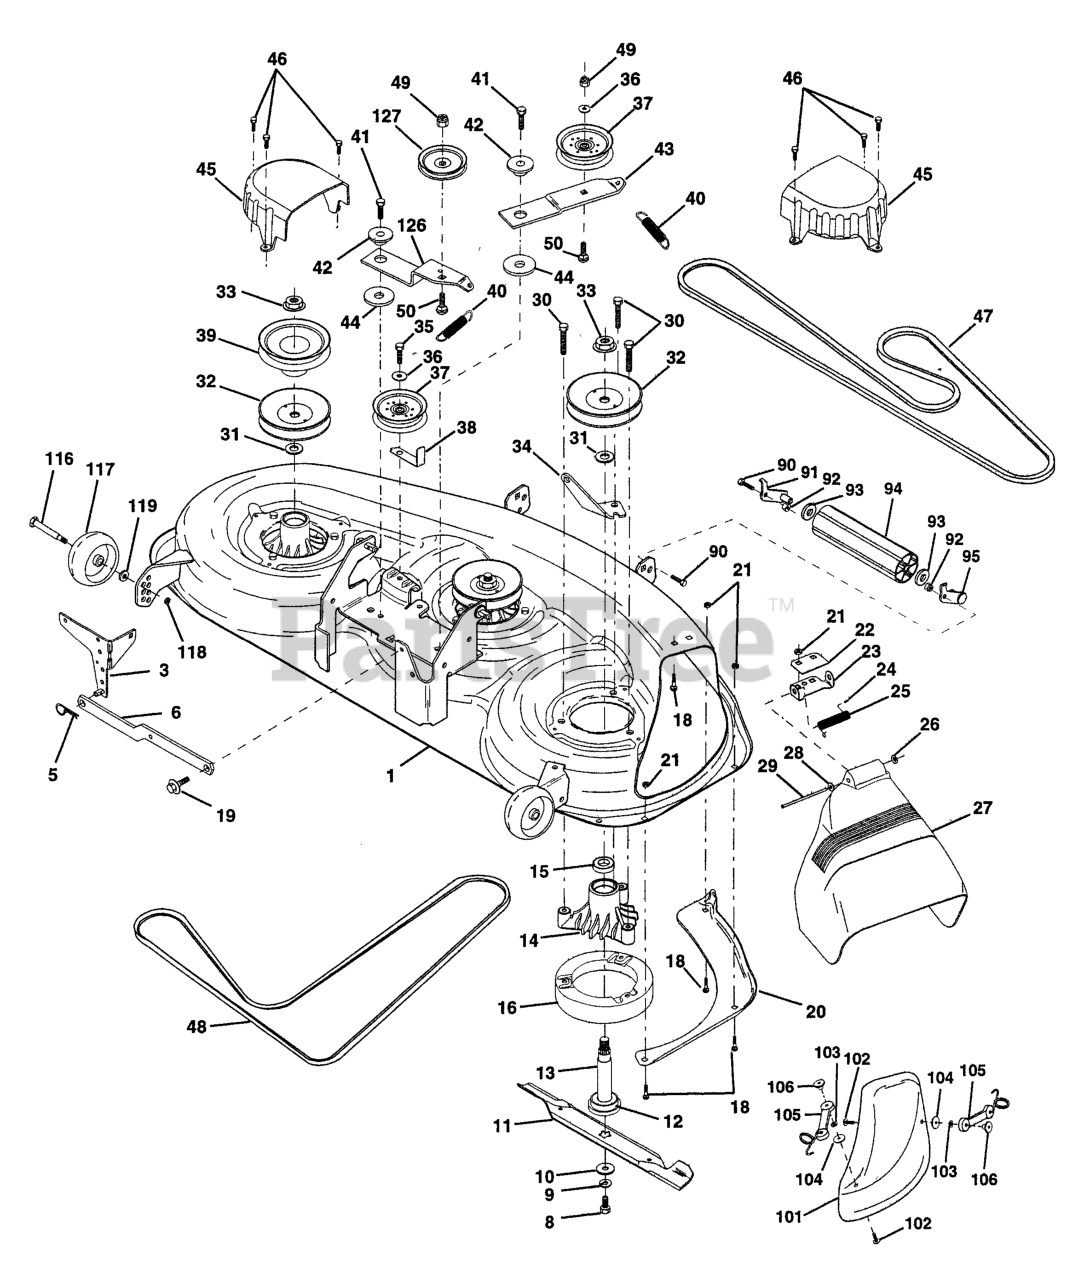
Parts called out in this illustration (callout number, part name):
1	DECK ASM, MOWER 46"
3	BRACKET SWAY BAR
5	RETAINER-SPRNG RB
6	REAR SUSP ARM
8	BLADE BOLT
9	LOCKWASHER
10	WASHER.BLADE
11	MULCH BLADE 46"
12	BEARING.BALL.#6204.(MANDREL)
13	SHAFT.ASM.W/BEARING
14	HOUSING.MANDREL.44/46" VENT
16	Stripper, Mower Round
18	BOLT
19	BOLT SHD 5/16-18
20	BAFFLE, VORTEX MOWER 46"
21	LOCKNUT
22	STIFFENER BRACKET
23	DEFLECTOR BRACKET
24	CAP-SLEEVE LT
25	SPRING TORSION
26	NUT PUSH M
27	SHIELD, DEFLECTOR MOWER
28	Washer 11/32 x 5/8 x 16 Ga.
29	ROD.HINGE
30	SCREW
31	WASHER
32	PULLEY, MANDREL
33	NUT
34	ANCHOR, SPRING DECK 46"
35	SCREW LT
36	WASHER
37	FLAT IDLER PULLEY
38	KEEPER
39	PULLEY.DRIVEN.DECK.46"
40	SPRING.SEC.44"VEN
41	SCREW
42	SPACER RETAINER
43	ARM IDLER DECK 46"
44	HARDENED WASHER
45	COVER MANDREL 46
46	SCREW.1/4-20X5/8
47	BELT V SECONDARY
48	V-BELT PRIMARY 50"
50	BOLT.3/8-16X1.50
90	BOLT
91	BRACKET LH (A)
92	NUT
93	Washer 17/32 x 7/8 x 16 Ga.
94	NOSE ROLLER
95	BRACKET RH (B)
101	COVER.MULCH.46"3-BLADE.(2 2)
102	SCREW
103	LOCKWASHER #10
105	LATCH ASSEMBLY
106	WELDNUT
116	BOLT, SHOULDER
117	WHEEL GAGE DONUT
118	LOCKNUT
119	WASHER.5/16.FLAT.STE.STD.
126	ARM IDLER PRIM 46
127	PULLEY.IDLER.4.25
